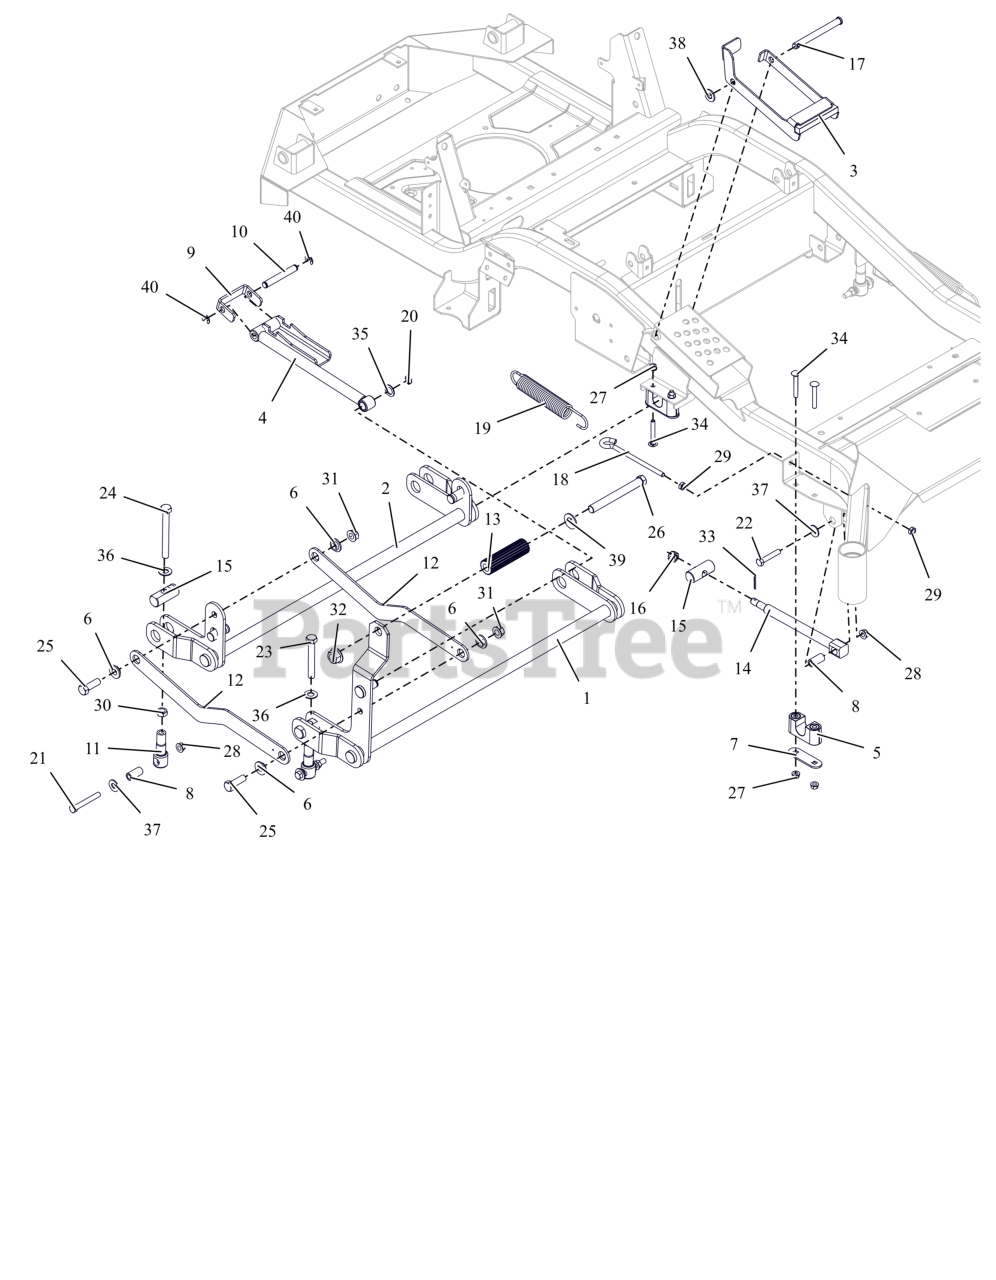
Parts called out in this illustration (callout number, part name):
1	WLDMT, FRONT DECK LIFT PIVOT
2	WLDMT, REAR DECK LIFT PIVOT
3	BRKT, HOC TRANSFER LOCK
4	WLDMT, HOC ARM
5	ASM-BUSHING, DECK LIFT
6	BSHG-FLG .515X.750X.395X1.120
7	PLATE, BEARING SUPPORT
8	SPACER, DECK LEVELING
9	BRKT, HOC LINE
10	ROD, HOC PIVOT
11	LINK, DECK LIFT FORMED
12	LINK, DECK LIFT
13	ROD, FOOT PEDAL (BLACK)
14	DRAG,LINK-HD
15	PIN, DECK LIFT
16	NUT-SL .50-13
17	PIN-SLIC .50X4.97X4.55 -ZCC
18	BOLT,.38-16 X 5.25-.62 DIA EYE
19	SG-TENS .162X1.25X8.25 WLD 25
20	RG-RTNG-EXT .625X.050
21	BLT, HEX .38-16X2.75 G8 ZCC
22	BLT,HEX .38-16X2.00 G5 ZCC
23	BLT, HEX .50-13X3.50F G5 ZCC
24	BLT, HEX .50-13X4.50F G8 ZCC
25	BLT,HEX .50-13X1.50 G5 ZCC
26	BLT, HEX .62-11X5.50 G5 FBP
27	NUT,LK-CTR-FLG .31-18 GF ZCC
28	NUT-LK-TOP-FLG .38-16 ZC120
29	NUT-JAM .375-16 G2 ZCC
30	NUT-JAM .500-13 G2 ZCC
31	NUT-LK-TOP-FLG .500-13 GF ZCC
32	NUT,FLG-TOP LK .625-11 FBP
33	PIN,CTR.12X1.25EXTPRSQCT ZC120
34	BLT, RHSSN.31-18X2.25 G5 ZCC
35	WSHR, FLT .630X1.005X.062 ZCC
36	WSHR, FLT .557X1.040X.102 ZCC
37	WSHR,FLT .438X1.00X.083 ZCC
38	WSHR,FLT .531X1.062X.095 ZCC
39	WSHRFLT 5/8SAE CARBHARD FBP
40	RG-RTNG-EXT .500X.042 (E)
